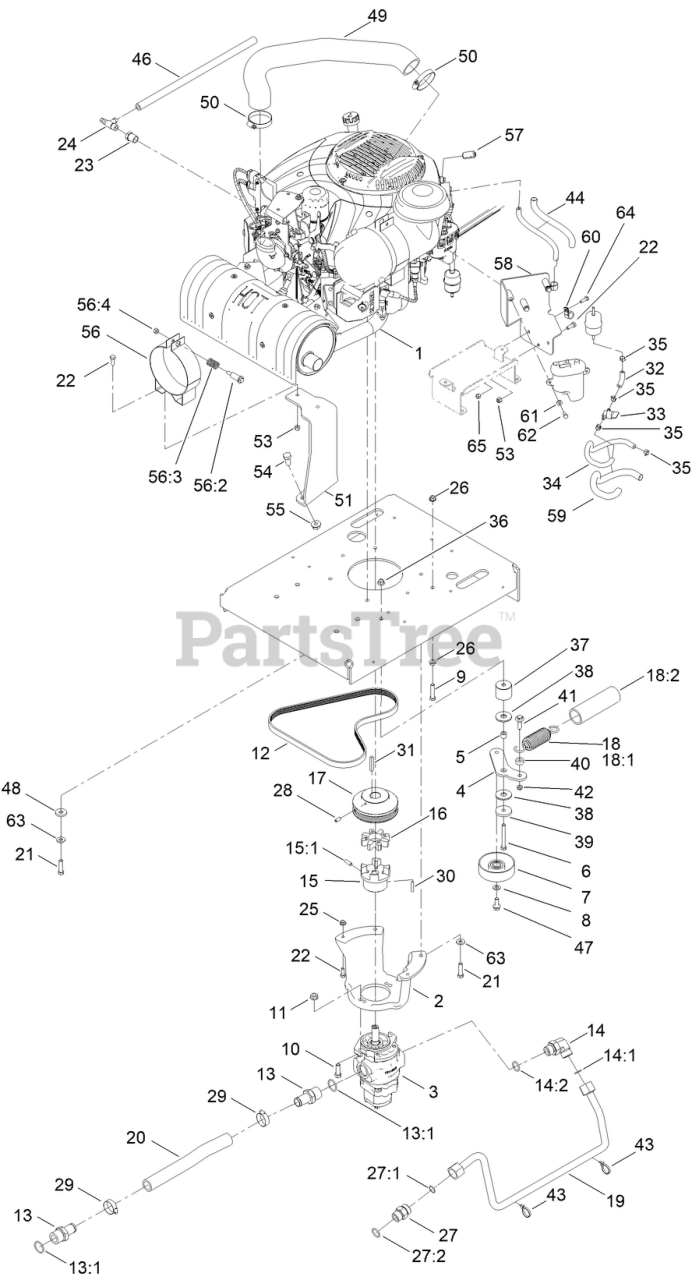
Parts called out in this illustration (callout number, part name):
1	ENGINE-KOHLER
2	MOUNT-PUMP
3	GEAR PUMP ASM
4	ARM-IDLER
5	BUSHING-LEVER, LIFT
6	SCREW-HH
7	PULLEY-IDLER
8	WASHER-FLAT
9	SCREW-HH
10	SCREW-HH
11	NUT-HF
12	BELT-V
13	FITTING-STR
13:1	O-RING
14	FITTING-ELBOW-90
14:1	O-RING
14:2	O-RING
15:1	SCREW-SET
16	SPIDER
18	SPRING AND RETAINER KIT
18:1	SPRING-EXTENSION
18:2	RETAINER-SPRING
19	TUBE-HYD
20	HOSE-SUCTION
21	SCREW-HH
22	SCREW-HH
23	BUSHING
24	VALVE-DRAIN, OIL
25	NUT-HF
26	NUT-HHF, WHIZ
27	FITTING-HYD, STRAIGHT
27:1	O-RING
27:2	O-RING
28	SCREW-SET, HSH
29	CLAMP-HOSE
30	KEY-SQUARE
31	KEY-SQUARE
32	HOSE-FUEL
33	VALVE-FUEL
34	HOSE-FUEL
35	CLAMP-HOSE
36	NUT-HF, NI
37	SPACER-IDLER
38	WASHER-FRICTION, COMPOSITE
39	WASHER-PLAIN
40	SPACER
41	SCREW-SHOULDER, HWH
43	TIE-CABLE
44	SLEEVE-THERMAL
47	SCREW-HHF
48	WASHER
49	HOSE-INTAKE, AIR
50	CLAMP-HOSE
51	PLATE-MOUNT, FILTER
53	NUT-LOCK, NI
54	SCREW-HH
55	NUT-HHF
56	BAND-MOUNTING, AIR CLEANER
56:3	SPRING
56:4	NUT-LOCK, NI
57	FERRITE-SNAP ON
58	BRACKET-PUMP, FUEL
59	SLEEVE-THERMAL
60	CLAMP-CABLE
61	WASHER-FLAT
62	SCREW-HH
63	WASHER-BELLEVILLE
64	SCREW-HH
65	NUT-LOCK, NI
